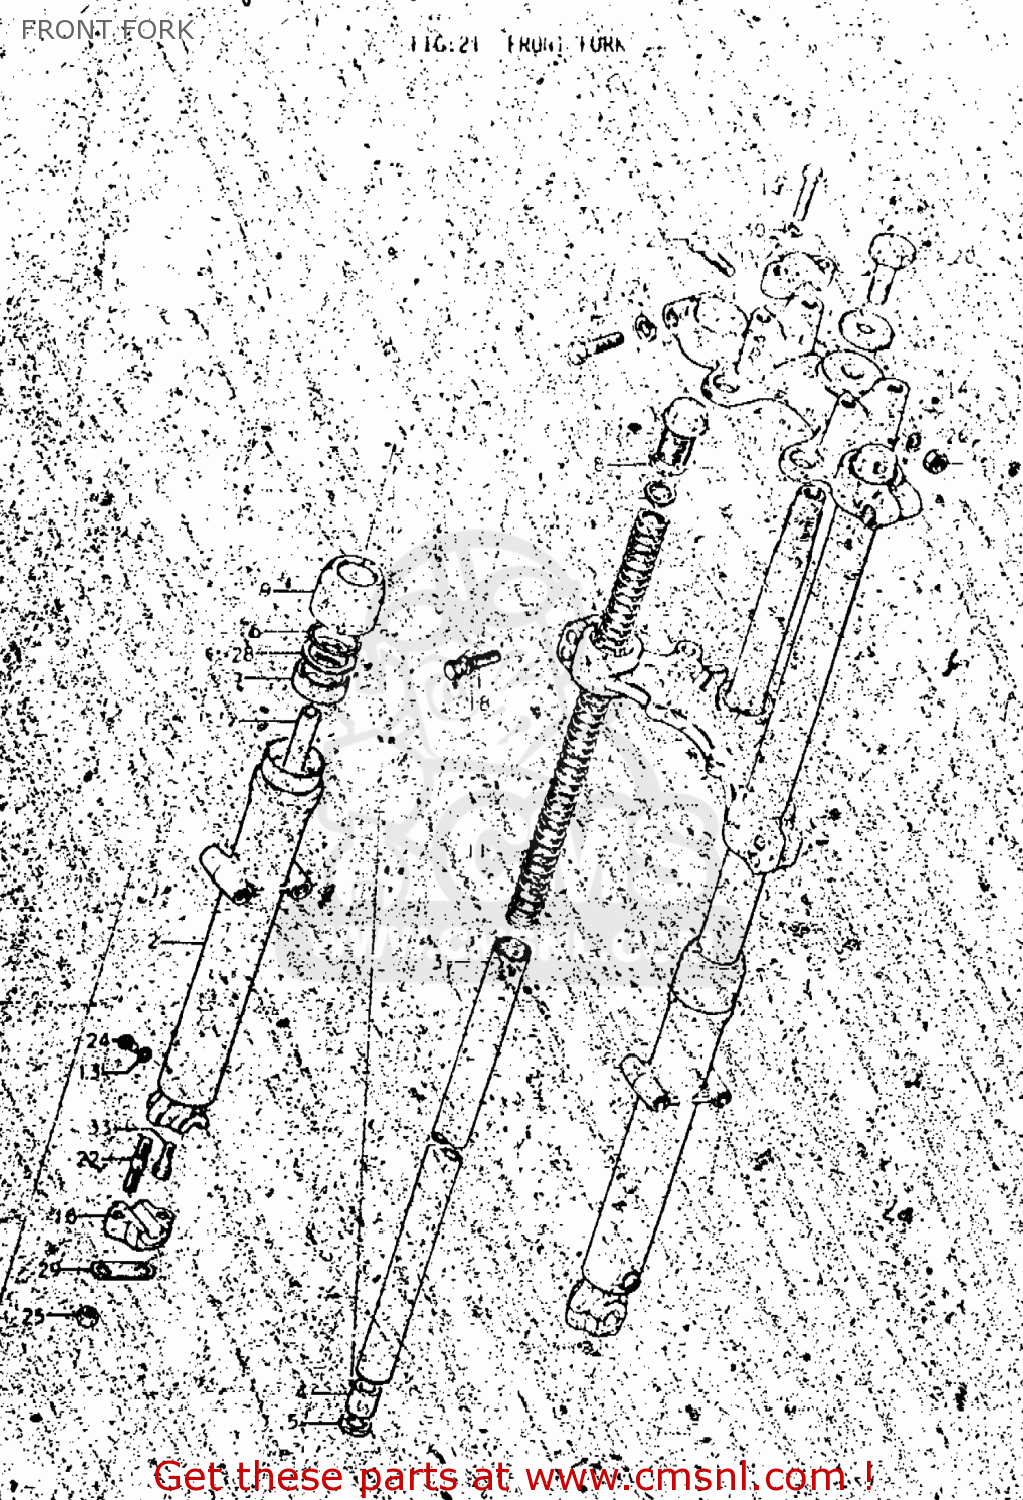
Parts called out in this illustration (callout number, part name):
0	DAMPER SET
1	TUBE,OUTER,RIGHT
2	TUBE,OUTER,LEFT
3	SEAL,OIL
4	CIRCLIP,FORK OIL SEAL
5	RING,FORK BACK UP
6	TUBE,FORK,INNER
7	CYLINDER,FRONT FORK
8	PIECE,OIL LOCK
9	GASKET (NAS)
10	BOLT,FORK CYLINDER(10X25)
11	STUD BOLT
12	HOLDER,AXLE
13	WASHER
14	NUT (8MM)
15	CAP,FORK INNER TUBE
16	O-RING,FORK FITTING BOLT
17	SCREW
18	GASKET,DRAIN,PLUG (NAS)
19	SPRING
20	SEAT,FRONT FORK SPRING
21	SNAP RING
22	PISTON L
23	LOCK WASHER
24	HEAD,STEERING STEM
25	BOLT
26	WASHER,STEM HEAD
27	CAP
28	HOLDER,HANDLEBAR
29	LOCK WASHER
30	Bolt
31	STEM,STEERING
32	STEM,STEERING
33	RACE,STEERING,INNER,UPPER
34	BOLT
35	LOCK WASHER
36	NUT
37	BOLT 10X50
38	LOCK WASHER
39	NUT
40	SEAL,DUST
41	BOLT
